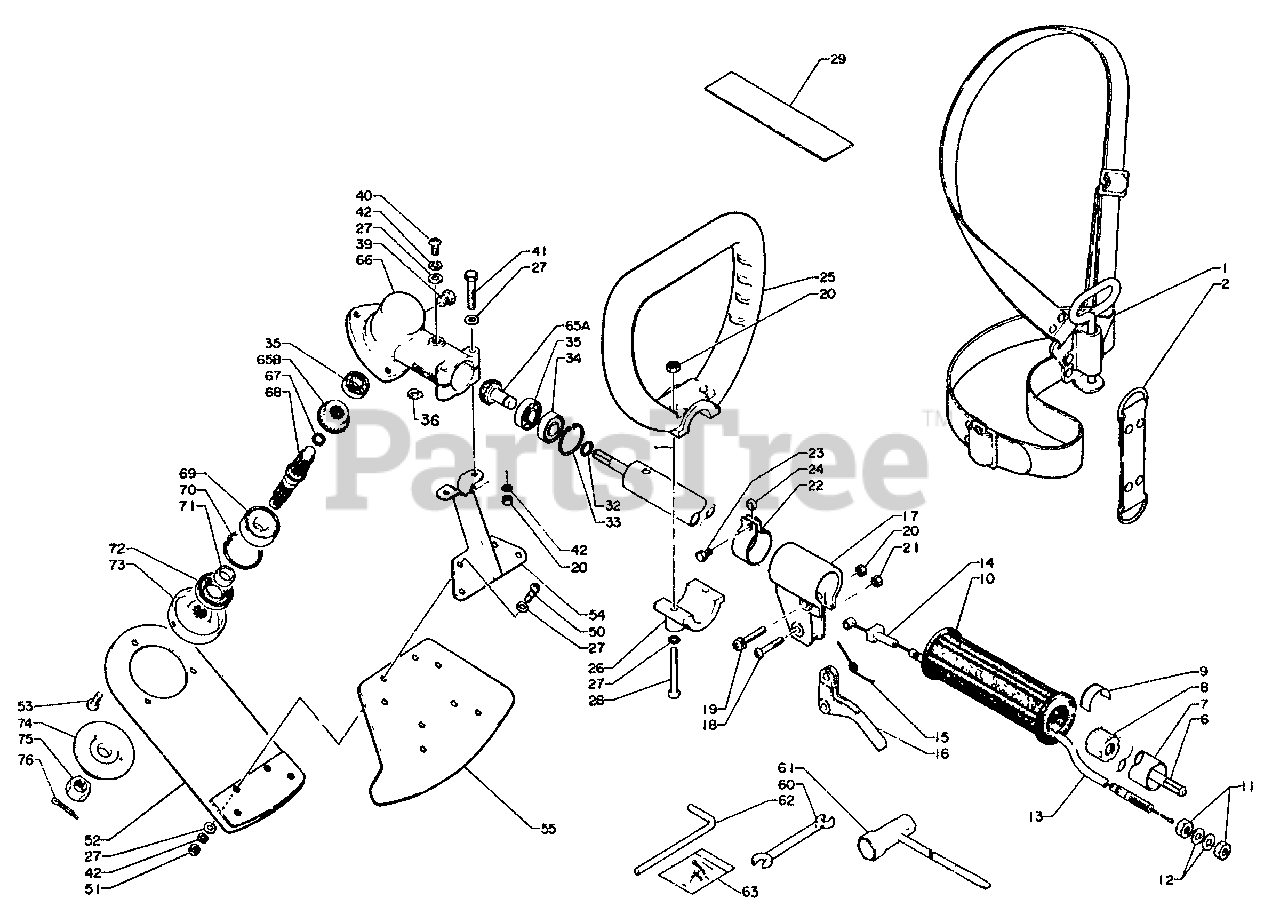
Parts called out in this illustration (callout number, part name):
1	SHOULDER STRAP ASSY
2	STRAP
6	DRIVESHAFT
7	MAIN PIPE ASSY
8	STOPPER
9	LABEL - ALIGNMENT
10	GRIP
12	WASHER 6.5×11.5×0.8
13	CABLE, THROTTLE
14	GUIDE, CABLE
15	SPRING, THROTTLE
16	TRIGGER, THROTTLE
17	BRACKET, TRIGGER
19	SCREW 5×30
20	NUT M5
21	LOCKNUT - 5
23	BOLT 5×18
24	SPACER, GUARD
25	LOOP HANDLE ASSY
26	LOOP HANDLE ASSY
27	WASHER, FLAT 5.5×10×0.8
28	SCREW 5×40
29	LABEL - CAUTION
32	RING, RETAINING
33	RING, SNAP Ø25
34	BEARING, BALL 609
35	BEARING, BALL 609
39	BOLT 8×8 SP
40	SCREW 5×10
41	BOLT 5×35 SP
42	WASHER, SPRING 5
50	SCREW 5×14
51	LOCKNUT - 5
54	BRACKET, SHIELD
55	SHIELD
60	SPANNER 8×10
61	T-WRENCH
62	TOOL, LOCKING 5×120 MM
63	PIN, COTTER 2×22 (PKG. OF 10)
65	GEAR SET
65A	GEAR SET
65B	GEAR SET
66	CASE, GEAR
67	RING, RETAINING - 12
68	SHAFT, GEAR
69	BEARING, BALL - 6201 C3
70	RING, SNAP Ø32
71	SPACER 11.8×15×9
72	SEAL, OIL 22
73	PLATE, ADAPTER - UPPER
74	PLATE, ADAPTOR - LOWER
76	PIN, COTTER 2×22
